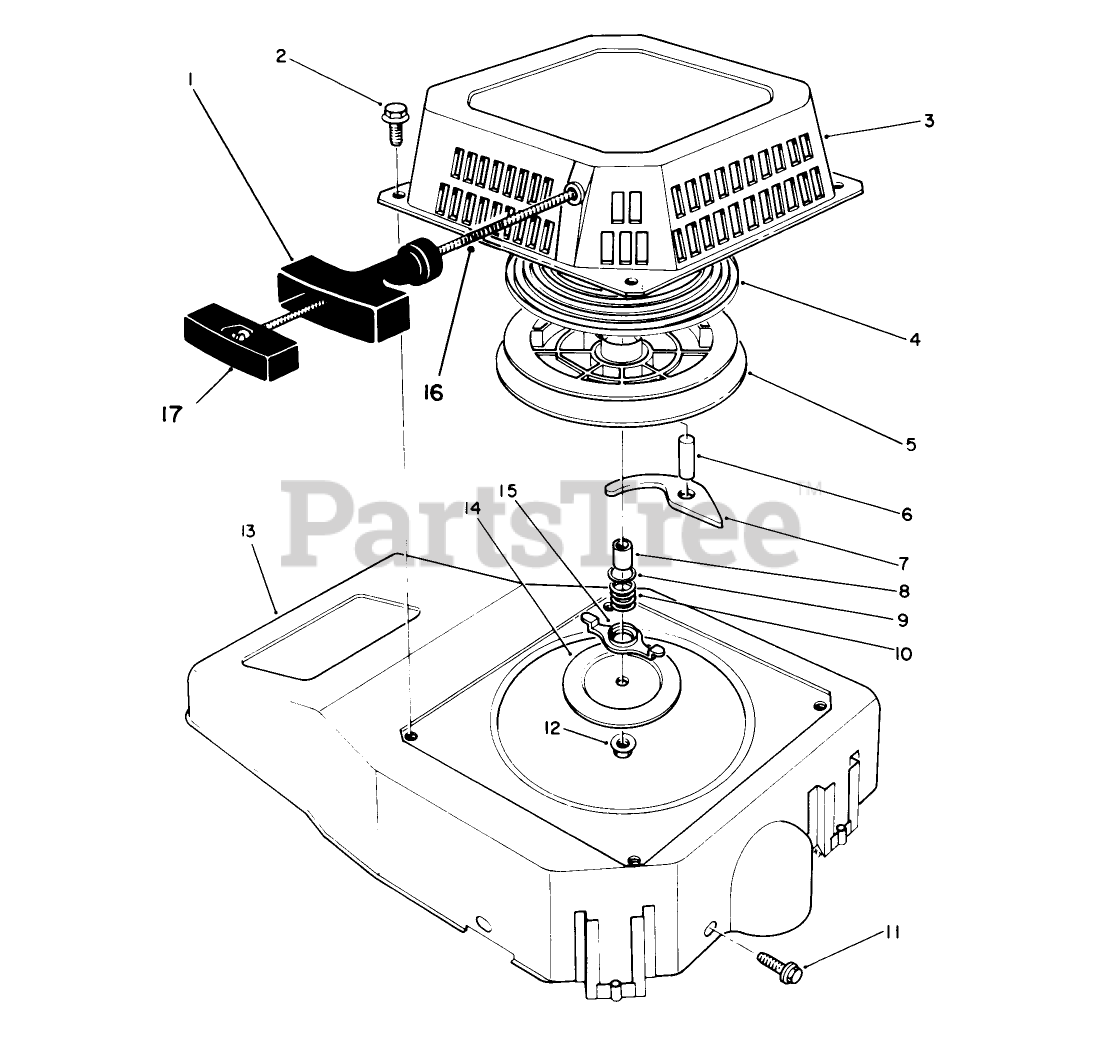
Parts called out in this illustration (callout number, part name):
1	HANDLE
2	SCREW-HHF
3	Case-Recoil
4	SPRING
8	Spacer
9	WASHER
10	Spring-Friction
13	SHROUD
14	PLATE
15	Guide-Paw
16	ROPE-STARTER
17	RETAINER HANDLE
